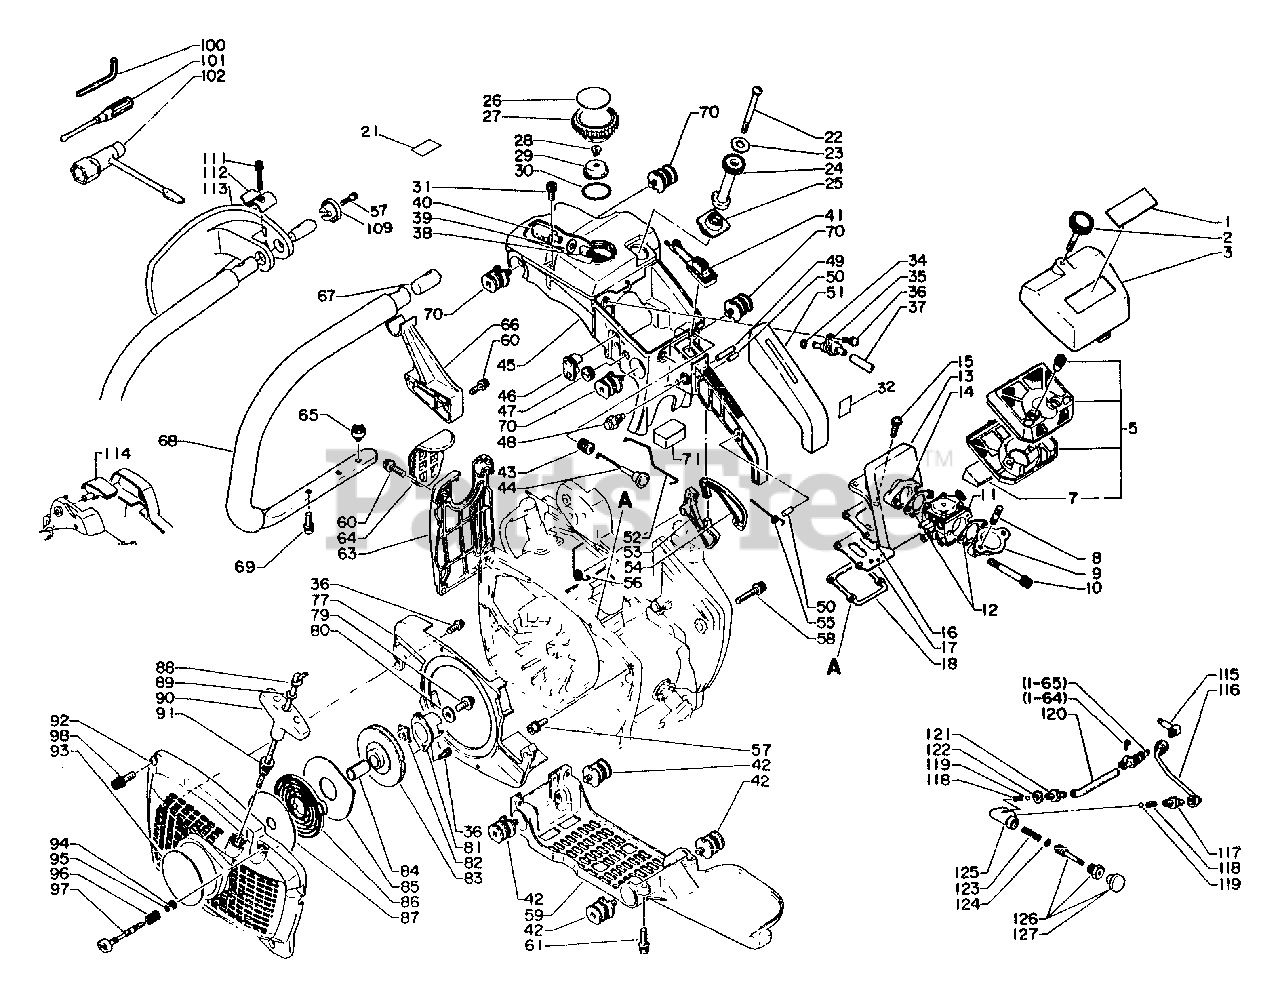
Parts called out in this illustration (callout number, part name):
1	LABEL
2	THUMBSCREW
3	AIR FILTER COVER ASSY
5	AIR FILTER ASSY
7	PAD, FOAM
8	STUD
9	MANIFOLD, INTAKE
10	BOLT 5×55
11	CARBURETOR - HDA
12	GASKET
13	GASKET - FOAM
14	ADAPTER, INTAKE
15	SCREW 5×18
16	GASKET
17	REED VALVE ASSY
18	GASKET
21	LABEL - NOISE
22	SCREW 5×75
23	LABEL, CAUTION
25	GROMMET, DIAL
26	LABEL - FUEL MIX
27	CAP
28	VALVE, CHECK
29	HOLDER, VENT
30	O-RING 29
31	BOLT M5×10
32	LABEL - CHOKE
34	O-RING 7 MM
35	CONNECTOR, PIPE
36	SCREW 4×10
37	PIPE, FUEL
38	PIPE, FUEL
39	WASHER 5.5×12×0.8
40	FILTER, FUEL
41	SWITCH, ON-OFF
42	CUSHION
44	ROD, CHOKE
46	GROMMET
48	LATCH, THROTTLE
49	PIN, SPRING 5×25
50	PIN, SPRING 4×13
51	GRIP
52	ROD, THROTTLE
53	TRIGGER, THROTTLE
54	LOCKOUT, THROTTLE
55	SPRING, LOCKOUT RETURN
56	SPRING, THROTTLE RETURN
57	BOLT 5×14
58	BOLT 5×30
59	SUPPORTER
60	BOLT 5×18
61	BOLT 5×20
63	BRACKET, HANDLE
64	COVER, BRACKET
65	CUSHION
66	BRACKET, HANDLE - UPPER
67	INSERT
68	HANDLE, FRONT
69	BOLT 5×14
70	CUSHION
71	PAD, FOAM
76	SCREW 4×8
77	PLATE, STARTER
79	SCREW 5×10
80	WASHER 5.2×16×1.0
81	PAWL CATCHER
82	RETAINER, ROPE
83	REEL, ROPE
85	PLATE, SIDE
86	SPRING, RECOIL
87	PLATE, STARTER
88	ROPE, STARTER
91	GUIDE, ROPE
92	CASE, RECOIL STARTER
93	LABEL - ECHO
94	E-RING 4
96	SPRING, COIL
97	ADJUSTER, IDLE
98	H.S.H. BOLT 5×20
100	L-WRENCH 4
101	SCREWDRIVER, PHILLIPS
102	WRENCH W/S, DRIVER
109	RETAINER
111	BOLT 5×40
113	GUARD
115	CONNECTOR
116	PIPE, OIL
117	CONNECTOR
118	SPRING, VALVE
119	VALVE, BALL
120	PIPE, OIL
121	CONNECTOR
123	PUMP SPRING
124	O-RING
126	PUMP PISTON
164	SCREW 3×8
165	CONNECTOR
